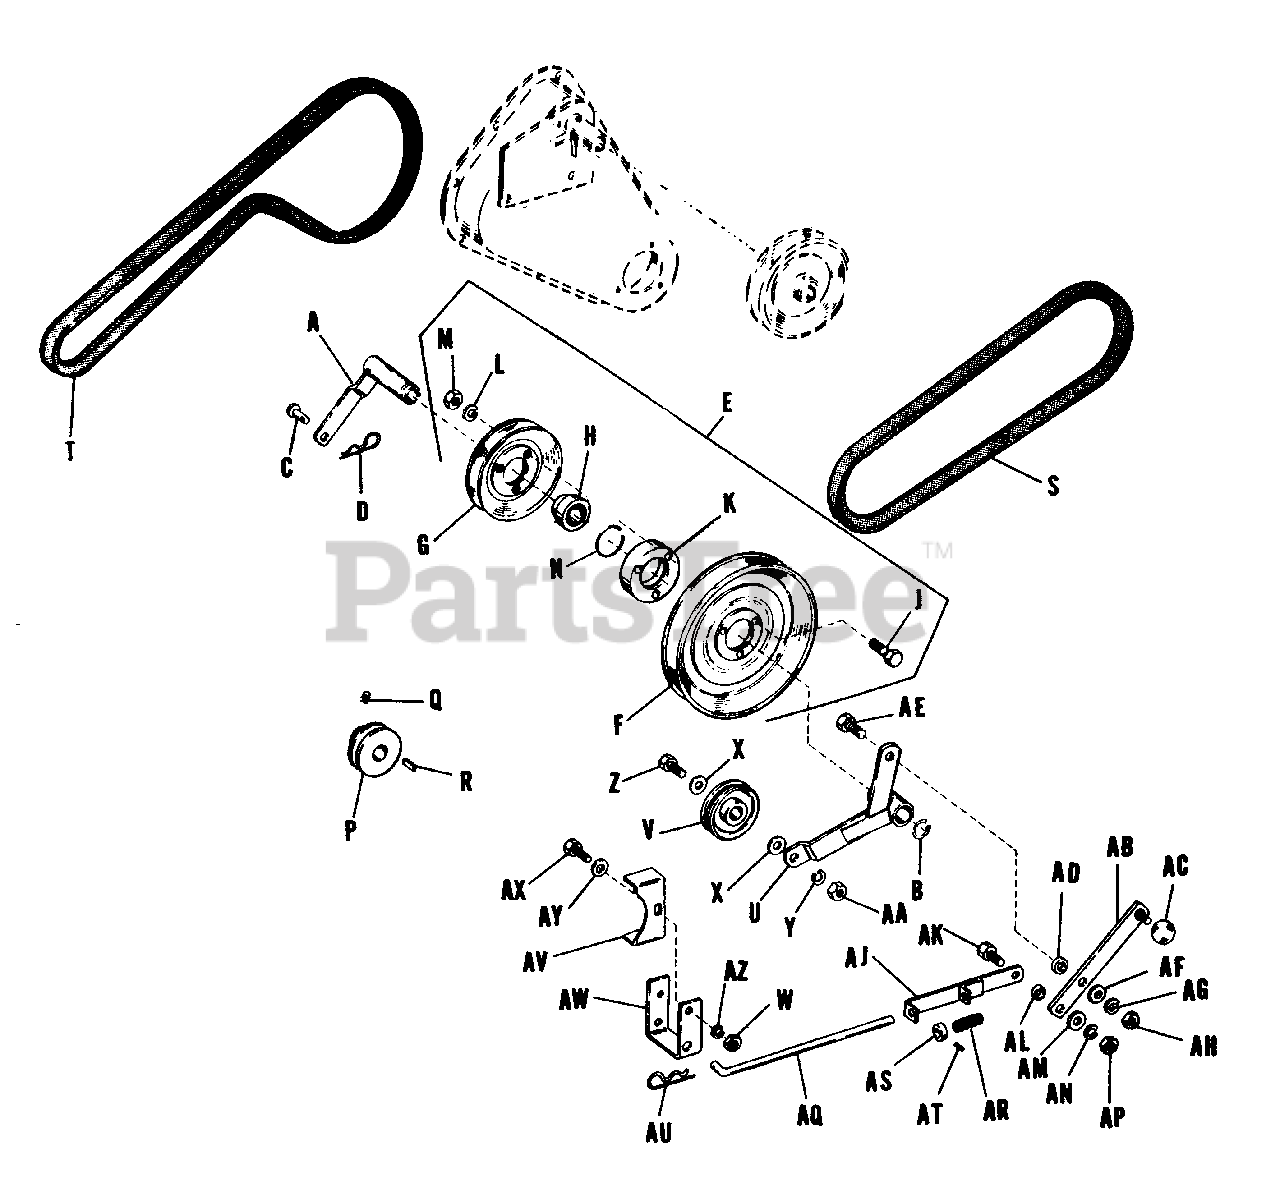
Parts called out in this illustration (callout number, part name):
A	Sleeve Assembly, Pulley
B	Ring, Snap
D	Clip, Spring
E	Pulley Assembly
F	Pulley, 10"
G	Pulley, 5 1/2"
J	Capscrew, Hex., 5/16"-18 NC x 1 3/4" lg.
L	Washer, Lock, 5/16"
M	Nut, Hex, Full, 5/16"-18 NC
N	Ring, Snap
P	Pulley, Tiller Drive
Q	Screw, Set, Cup Point, Socket Head, 5/16"-18 NC x 5/16" lg.
U	Lever Assembly, Idler
V	Pulley, Idler
W	Nut, Hex, Full, 3/8"-16 NC
X	Washer, Plain, 5/16"
Y	Washer, Lock, 3/8"
Z	Capscrew, Hex, 3/8"-16 NC x 1 1/4" lg.
AA	Nut, Hex, Full, 3/8"-16 NC
AB	Lever Assembly, Clutch
AE	Capscrew, Hex, 3/8"-16 NC x 1" lg.
AF	Washer, Plain, 3/8"
AG	Washer, Lock, 3/8"
AH	Nut, Hex, Full, 3/8"-16 NC
AJ	Guide Assembly
AK	Capscrew, Hex, 3/8"-16 NC x 7/8" lg.
AM	Washer, Plain, 3/8"
AN	Washer, Lock, 3/8"
AP	Nut, Hex, Full, 3/8"-16 NC
AT	Screw Set, Square Head, Cup Point, 1/4"-20 NC x 3/8" lg.
AU	Clip, Spring
AV	Release, Belt
AW	Bracket, Belt Release
AX	Capscrew, Hex, 3/8"-16 NC x 7/8" lg.
AY	Washer, Plain, 3/8"
AZ	Washer, Lock, 3/8"
